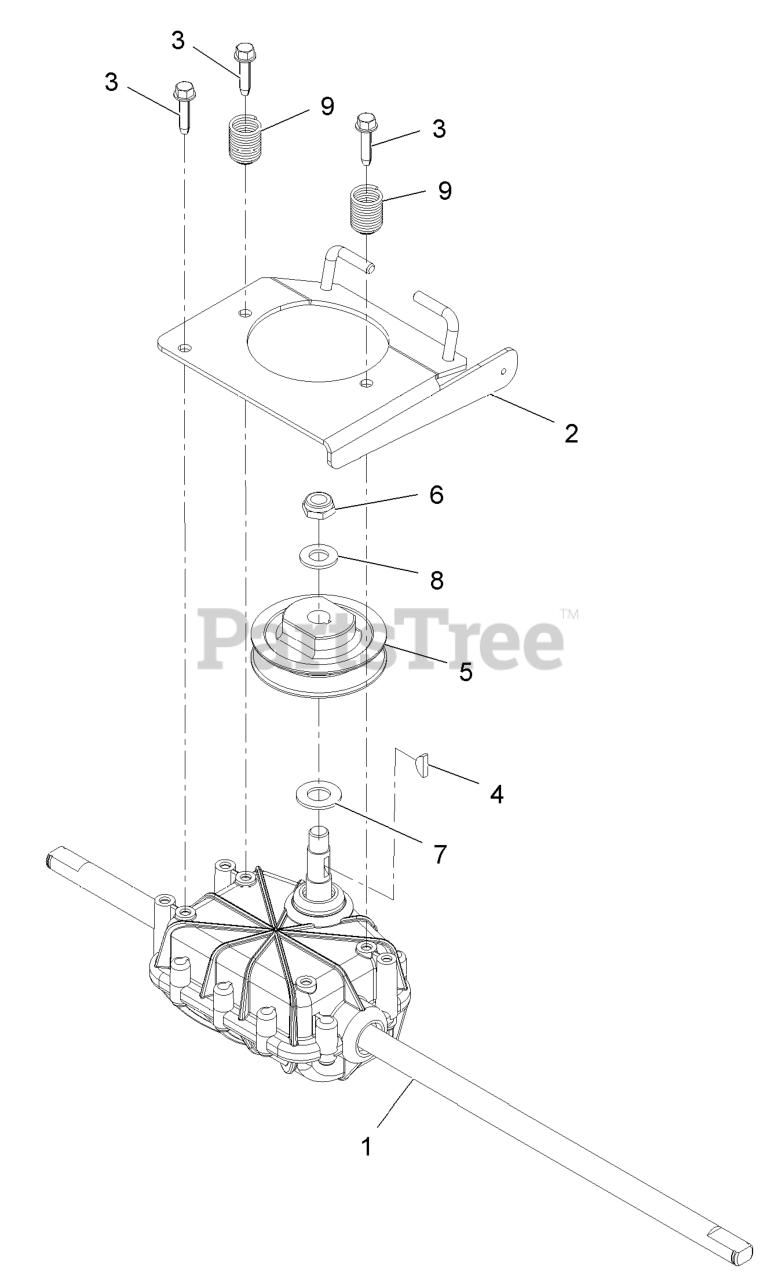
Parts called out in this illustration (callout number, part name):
2	TRANSMISSION PLATE ASM
3	SCREW-SPECIAL
4	KEY-WOODRUFF
6	NUT-HEX
7	WASHER-THRUST
8	WASHER-FLAT
9	SPRING,COMPRESSION
